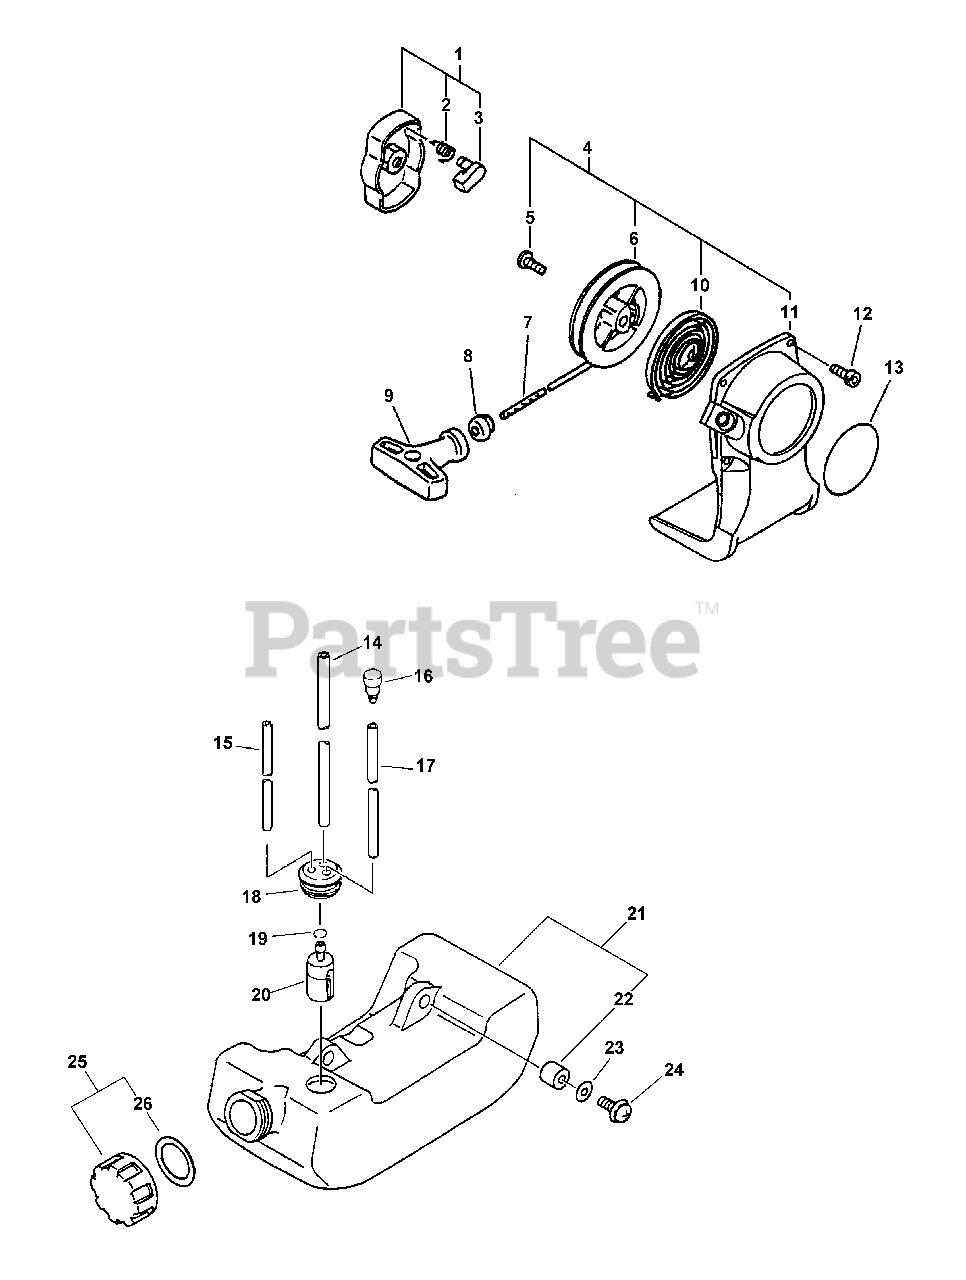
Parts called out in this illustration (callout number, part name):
1	PAWL ASSY, STARTER
2	SPRING, RETURN
3	PAWL, STARTER - BLACK
4	STARTER ASSY
5	SCREW
6	REEL, ROPE
7	ROPE, STARTER 3.0×1000
8	GUIDE, ROPE
9	GRIP, STARTER
10	SPRING, RECOIL
11	CASE, RECOIL STARTER
12	BOLT 4×16
13	LABEL, ECHO
14	PIPE, FUEL
15	PIPE, FUEL RETURN 3×6×90 MM CLEAR
16	VENT ASSY
17	PIPE, FUEL VENT
18	GROMMET, FUEL Ø5
19	CLIP 6 MM
20	FILTER, FUEL
21	TANK, FUEL
22	SPACER 6.2×7.8×6
23	WASHER 5.5×12×0.8
24	SCREW 5×16
25	CAP ASSY, FUEL
26	GASKET, FUEL CAP
